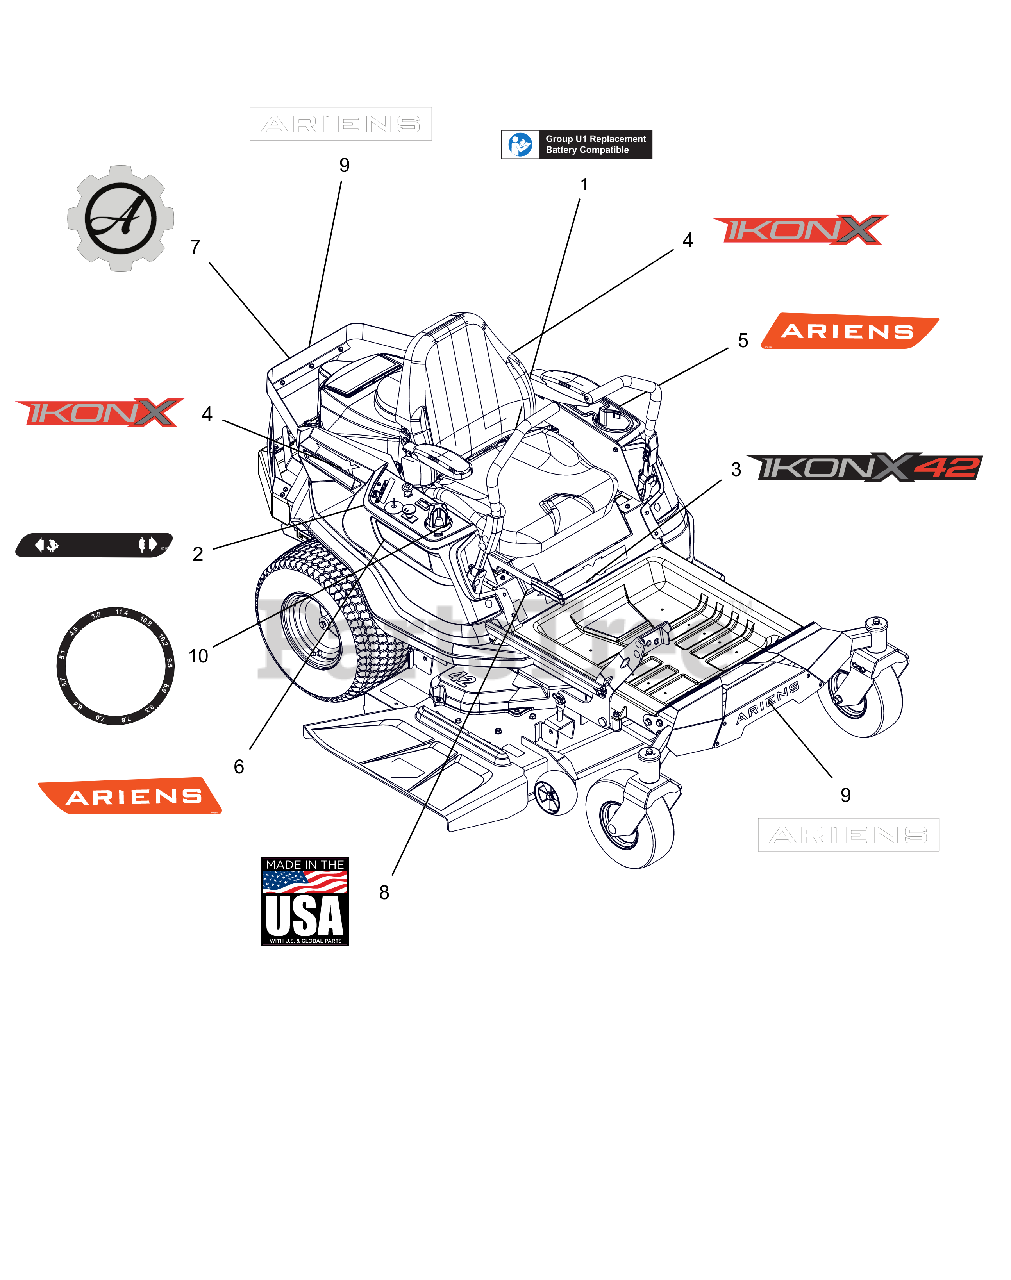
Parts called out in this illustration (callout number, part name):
1	DECAL, U1 BATTERY REPLACEMENT
2	DECAL, DASH DECAL
3	DECAL, IKON-X 42"
4	DECAL, IKON
5	DECAL, FENDER LH
6	DECAL, FENDER RH
7	DECAL, ARIENS-GEAR BADGE -THK
8	DECAL, MADE IN USA
9	DECAL - ARIENS 9.625"
10	DECAL, CUT HEIGHT - IKON CE
